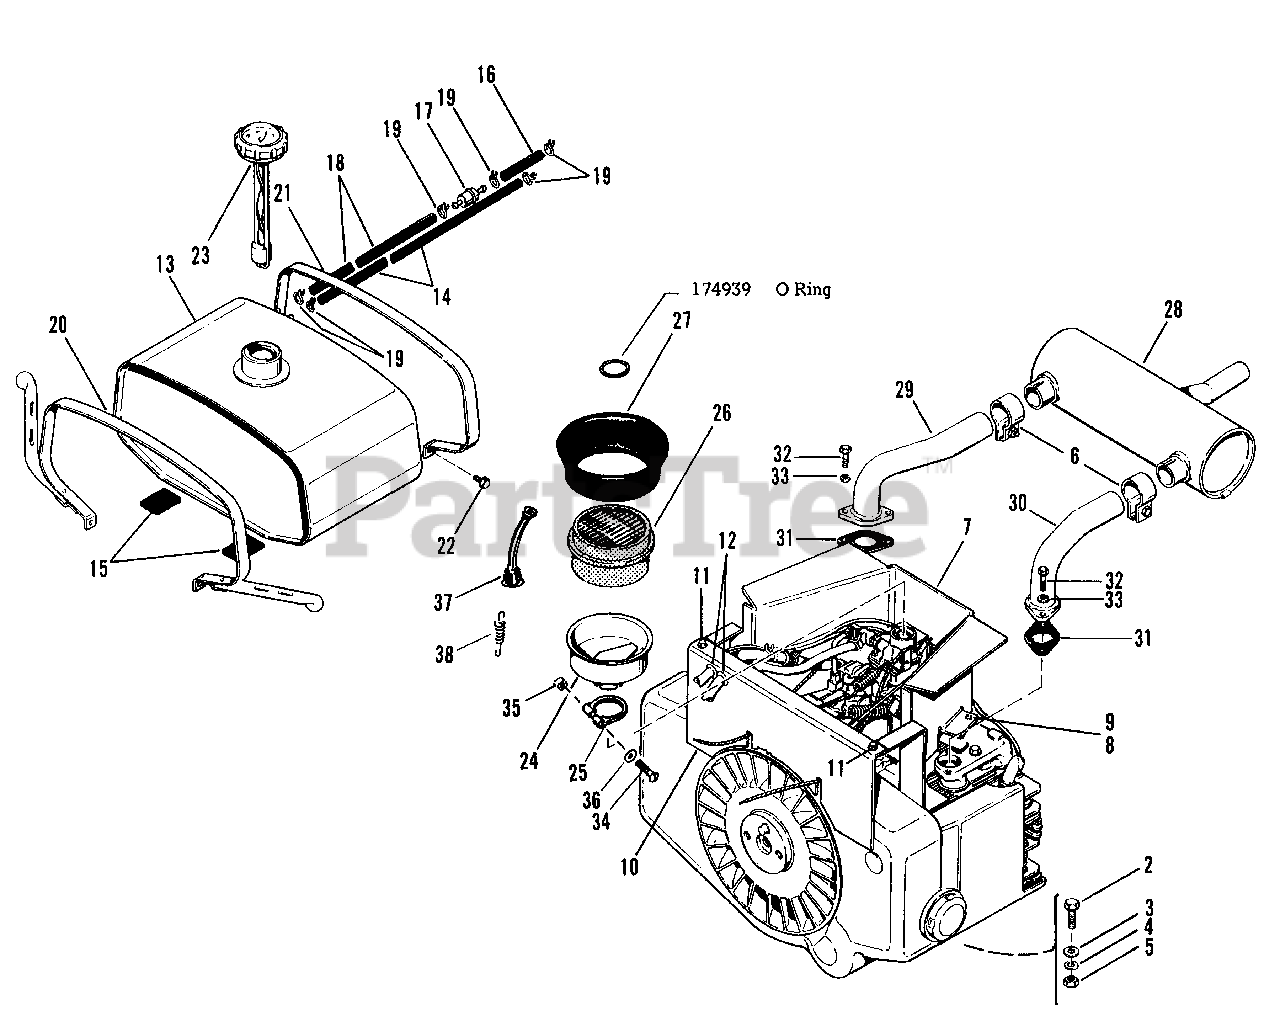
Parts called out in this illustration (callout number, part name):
2	Hex Capscrew, 7/16"-14 x 1-1/2" lg.
3	Plain Washer, 7/16"
4	Lock Washer, 7/16"
5	Hex Nut, Full, 7/16"-14
6	Clamps
7	Heat Shield Assembly
8	Rd. Hd. Screw, No. 10-32 x 3/8" lg.
9	Lock Washer No. 10
10	Shroud, Front
11	Self Tapping Screw, 1/4"-20 x 1/2"
13	Fuel Tank Assembly
14	Fuel Line, return
15	Felt Gasket
16	Fuel Line
17	Gas Filter
18	Fuel Line
20	Tank Strap Assembly-Real
21	Tank Strap-Front
22	Thread Forming Screw, 1/4"-20 x 1" lg.
24	Funnel Assembly
26	Air Cleaner
27	Air Cleaner Seal
29	Exhaust Pipe Assembly, L.H.
30	Exhaust Pipe Assembly, R.H.
32	Hex Capscrew, 5/16"-18 x 1-1/4" lg. (grade 5)
33	Lock Washer, 5/16"
36	Plain Washer
37	Breather Tube
